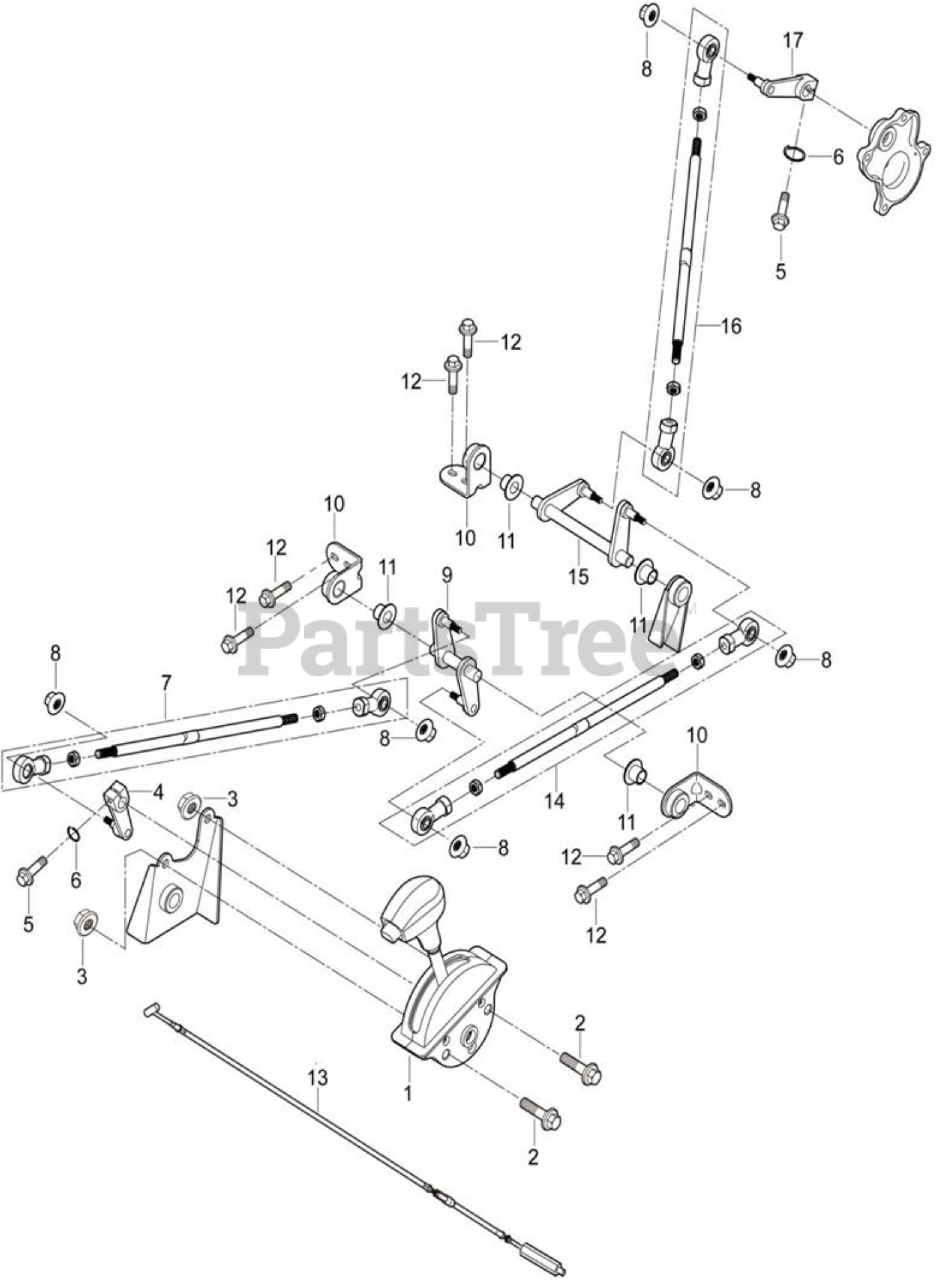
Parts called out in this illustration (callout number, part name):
1	Gear Shifter Assembly
2	Hexagon Flange BoltM8X45
3	Hexagon Flange Nut M8
4	Gearshift arm
5	Hexagon Flange BoltM6X20
6	Spring Washer-8
7	Gear Shift Rod I
8	Hexagon Flange Locked Nut M6
9	steering lever I,Gearshift
10	Shift steering arm installation I
11	Nylon Bushing 12X15.5
12	Hexagon Flange Bolt M6X16
13	Spacing Cable Assy D, Reverse Gear
14	Gear Shift Rod II
15	Steering Arm II,Gear shifting
16	Gear Shift Rod III
17	Gearshift arm
